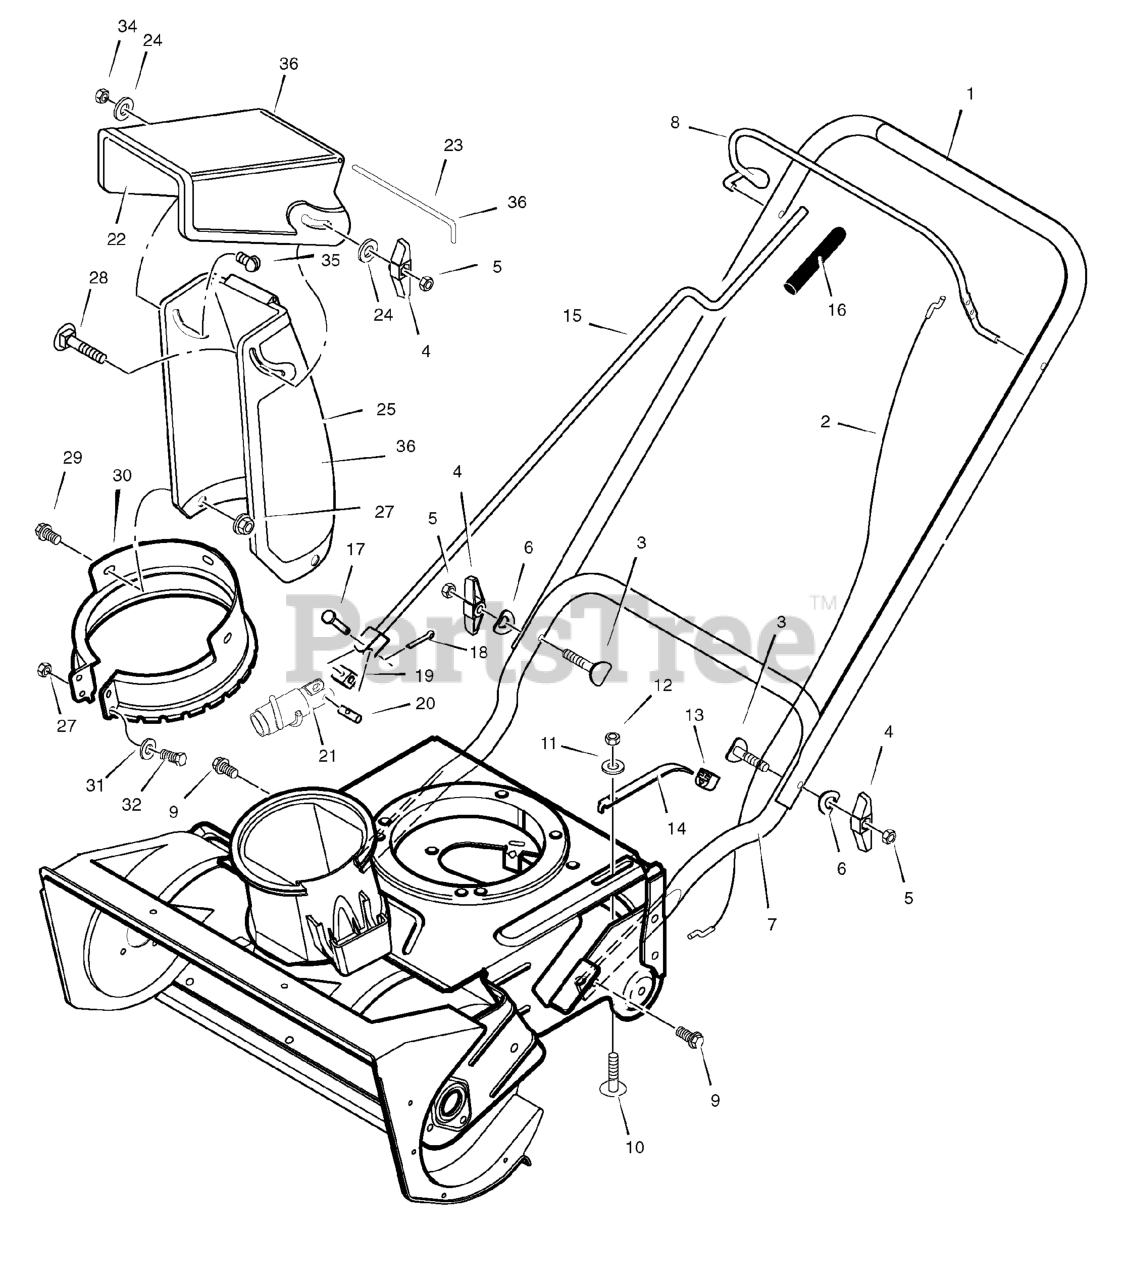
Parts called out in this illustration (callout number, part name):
1	HANDLE, Upper
2	CABLE, Auger Drive
3	BOLT, 5/16-18 X 2.00
5	NUT, Hex, 5/16-18
7	HANDLE, Lower
8	LEVER, Auger Drive
9	CAPSCREW, Hex Washer Head, 5/16-18 x 3/4
10	BOLT, 1/4-20 x 5/8
12	NUT, Hex, Nylock, 1/4-20
13	BUSHING, Tensioner
14	BRACKET, Cable Tensioner
15	ROD, Crank
16	GRIP, Crank Rod
17	PIN, Clevis
18	PIN, Cotter
19	BLOCK, Universal Pivot
21	GEAR, Worm
22	DEFLECTOR
23	PIN, Pivot
24	WASHER
25	CHUTE, Discharge
27	NUT, Hex Flange, Centerlock, 1/4-20
28	BOLT, 5/16-18 x 1-1/4
29	CAPSCREW, Hex Head, 1/4-20 x 1/2
30	RING, Chute
31	WASHER
32	CAPSCREW, Hex Head, 1/4-20 x 3/4
34	NUT, HEX, Centerlock, 5/16-18
35	CAPSCREW, 5/16-18 x 3/4
36	COMPLETE DISCHARGE CHUTE ASSEMBLY
